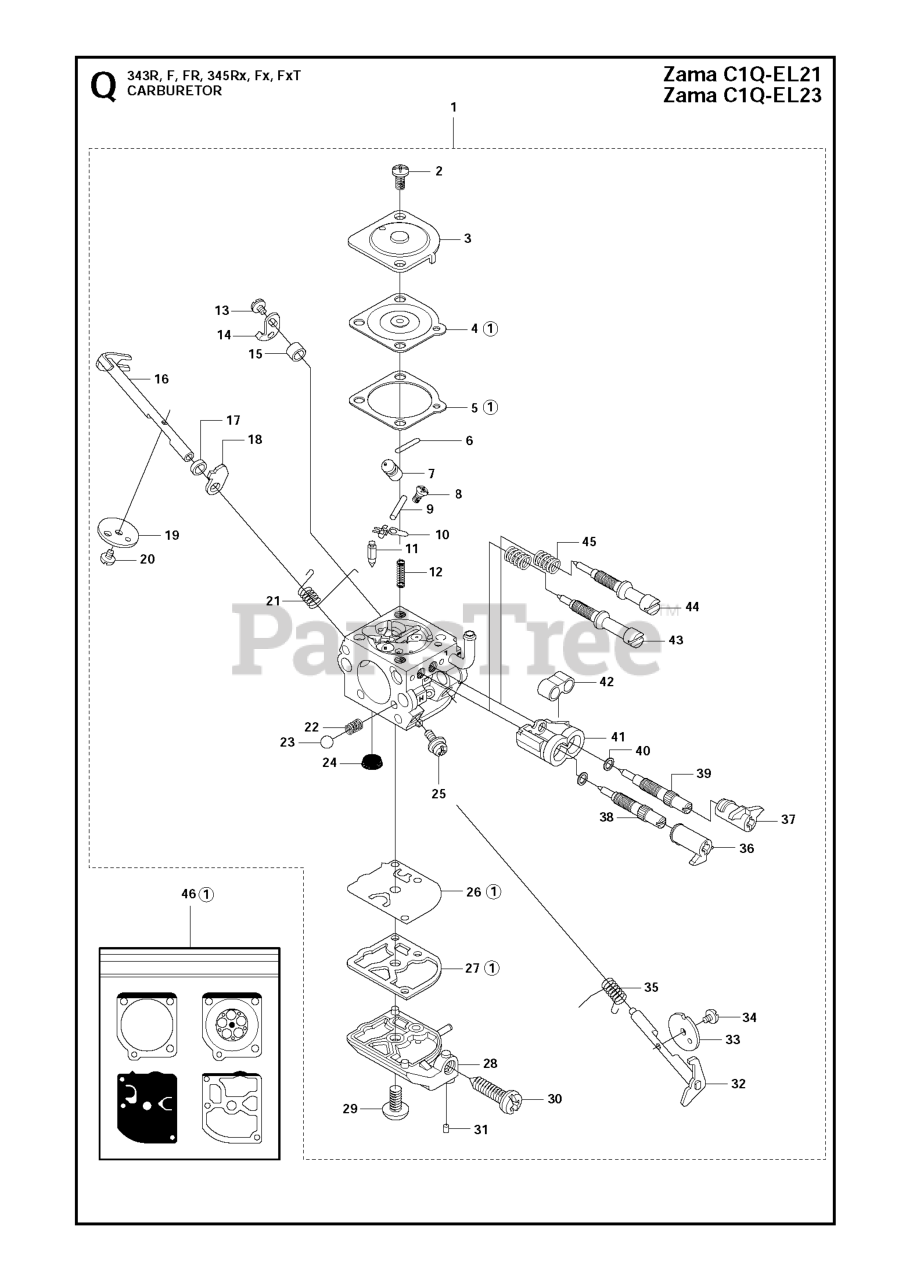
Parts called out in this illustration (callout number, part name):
1	OIL PUMP
3	PUMP PISTON
4	WASHER 6.1X9
6	SPRING CLIP
8	SCREW ITXSCM M5X16 T27 12.9 T
9	PUMP PINION
11	OIL PRESSURE HOSE
11	GROMMET
14	OIL SCREEN
15	RETAINING RING
17	CLUTCH DRUM ASSY
18	22273 Sprocket 3/8"x8T
18	68210 RIMSPROCKET
19	CLUTCH DRUM BEARING
20	CLUTCH ASSY M14X1.25-6H
